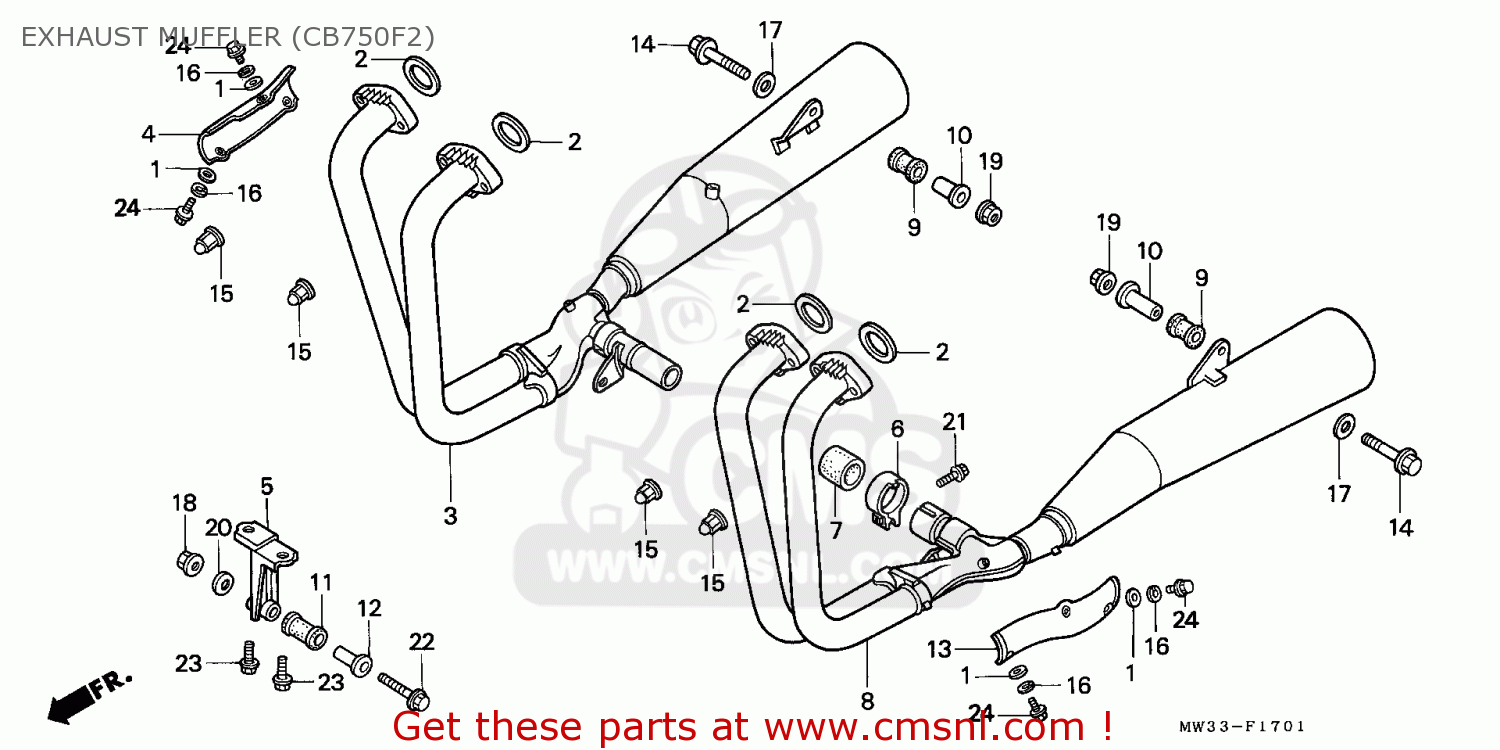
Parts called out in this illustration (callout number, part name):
1	WASHER,PIVOT
2	GASKET,EXH PIPE (NAS)
3	MUFFLER COMP.,R.E
4	COVER,R.EX.JOINT
5	STAY,CENTER MUFF
6	BAND,R.RR.MUFFLER
7	PACKING MUFFLER (NAS)
8	MUFFLER COMP.,L.E
9	RUBBER,MUFFLER
10	COLLER,MUFFLER
11	RUBBER,CHAMBER MO
12	COLLAR,CHAMBER MO
13	COVER,L.EX.JOINT
14	BOLT,FLANGE,10X50
15	NUT,CAP,7MM
16	WASHER,SPG.,6MM
17	WASHER,SPL.10MM
20	WASHER,PLAIN, 8MM
21	BOLT,FLANGE,8X40
22	BOLT,FLANGE,8X45
23	BOLT,FLANGE,10X20
24	BOLT,FLANGE,6X10
